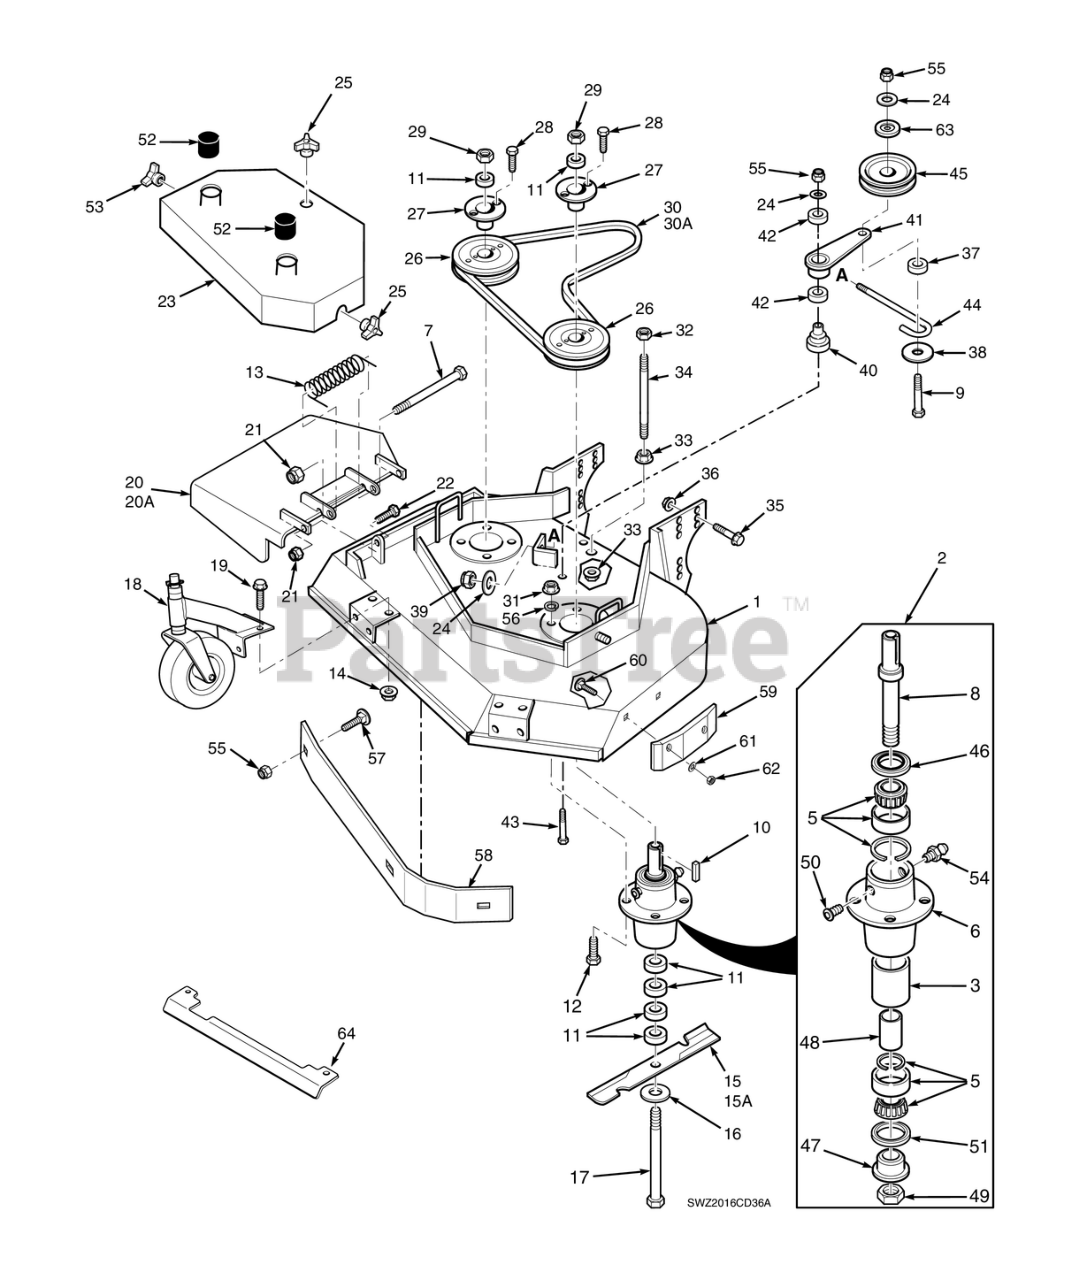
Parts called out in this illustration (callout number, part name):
1	Cutter Deck w/Decals
2	Cutter Spindle Assembly
3	Spacer, Outside, Cutter Spindle
5	Tapered Bearing Set (Two Bearings W/Race)
6	Housing, Spindle
7	Bolt, 5/16-18 x 4-3/4" Hex Head
8	Spindle Shaft, Tapered Brng
9	Capscrew, Hex Head 3/8-16 x 3-3/4"
10	Key, 1/4 x 1/4 x 2.0"
11	Spacer, Cutter Blade - Small
12	Bolt, Hex Head 5/16-18 x 1-1/2" Grade 8
13	Spring, Discharge Chute
14	Nut, Serrated Flange 5/16-18 (Right Front Engine Mounting, Briggs and Kohler Only)
15	Cutter Blade 18" (marbane)
15A	Cutter Blade 18" Hi Lift (marbane)
16	Flatwasher, 5/8-.688 x 1-3/4 x .134 HD
17	BOLT, HEX HEAD, 5/8-11 X 9-1/2 GR.5
18	Caster Assembly
19	Capscrew, 5/16-18 x .75 Serrated Flange Hex Head
20	Discharge Chute Advantage - Small
21	HEX NUT, ELASTIC STOP LOCK, 5/16-18
22	Bolt, Heax Head 5/16-18 x 1" (48V / 52V)
23	Belt Cover Assy (Incl. Decal)
24	Flatwasher, 3/8 (.391 x .938 x .105 HD) Grade 8
25	WINGNUT, PLASTIC 3/8-16 X .875
26	Pulley, 5.75 O.D. (Gasoline Engines)
27	Hub, Tapered 1-1/8" Bore
28	Bolt, Hex Head 1/4-20 x 1" Grade 8 Black
29	Hex Locknut, Elastic Stop, 3/8-16
30	BELT CUTTER DK SM36
31	Lock Nut, 5/16-18 Elastic Stop Grade 8
32	Bolt, Hex Head 3/8-16 x 1" Ser. Flg.
33	NUT, 3/8-16 SERRATED FLANGE HEX HEAD
34	Bolt, 5/16-18 x 1" Hex Head
35	Serr. Fl. Hex Head Capscrew, 1/2-13 x 1-3/4
36	Nut, Elastic Stop 1/2-13, (STT-52 & STTII-52)
37	SPACER, J-PULL ROD
38	Flatwasher, 3/8 (.375 x 1-1/2" x 16 ga.)
39	HEX NUT, ELASTIC STOP LOCK, 3/8-16
40	Pivot, Idler - Short
41	Idler Arm Assy.
42	BEARINGS, BALL, NEUTRAL RETURN
43	Capscrew, Hex Head 3/8-16 x 3.25"
44	J-Hook, Idler Pulley
45	Idler Pulley, Belt Clutch
46	SEAL, 2.00 O.D. X 1.50 BORE
47	SPINDLE BUSHING, BOTTOM
48	SLEEVE, CUTTER SPINDLE
49	Nut , Spec ial 1 -1/ 1 6 - 1 8
50	RELIEF FITTING, TAPERED BEARING SPINDLE
51	Seal, 2.00" O.D. x 1.625" Bore
53	Wing Nut, 3/8-16 (Small) Top side
54	GREASE FITTING, STR. 1/4-28 SELF TAP.
55	HEX NUT, ELASTIC STOP LOCK, 3/8-16
56	Lockwasher, 5/16 (.317 x .586 x .078) Helical Spring
57	Carriage Bolt, 3/8-16 x 1.0"
58	Baffle, Flange - 36A
59	Pad, Deck Wear
60	Bolt, 5/16-18 x .75 RHSN Carriage
61	Flatwasher, 5/16-.344 x .688 x .065 (48V / 52V)
62	Nut, Center Lock, 5/16-18(32)
63	Quick Pin, 5/16" Dia.
64	Heatshield, 16" Small Frame
